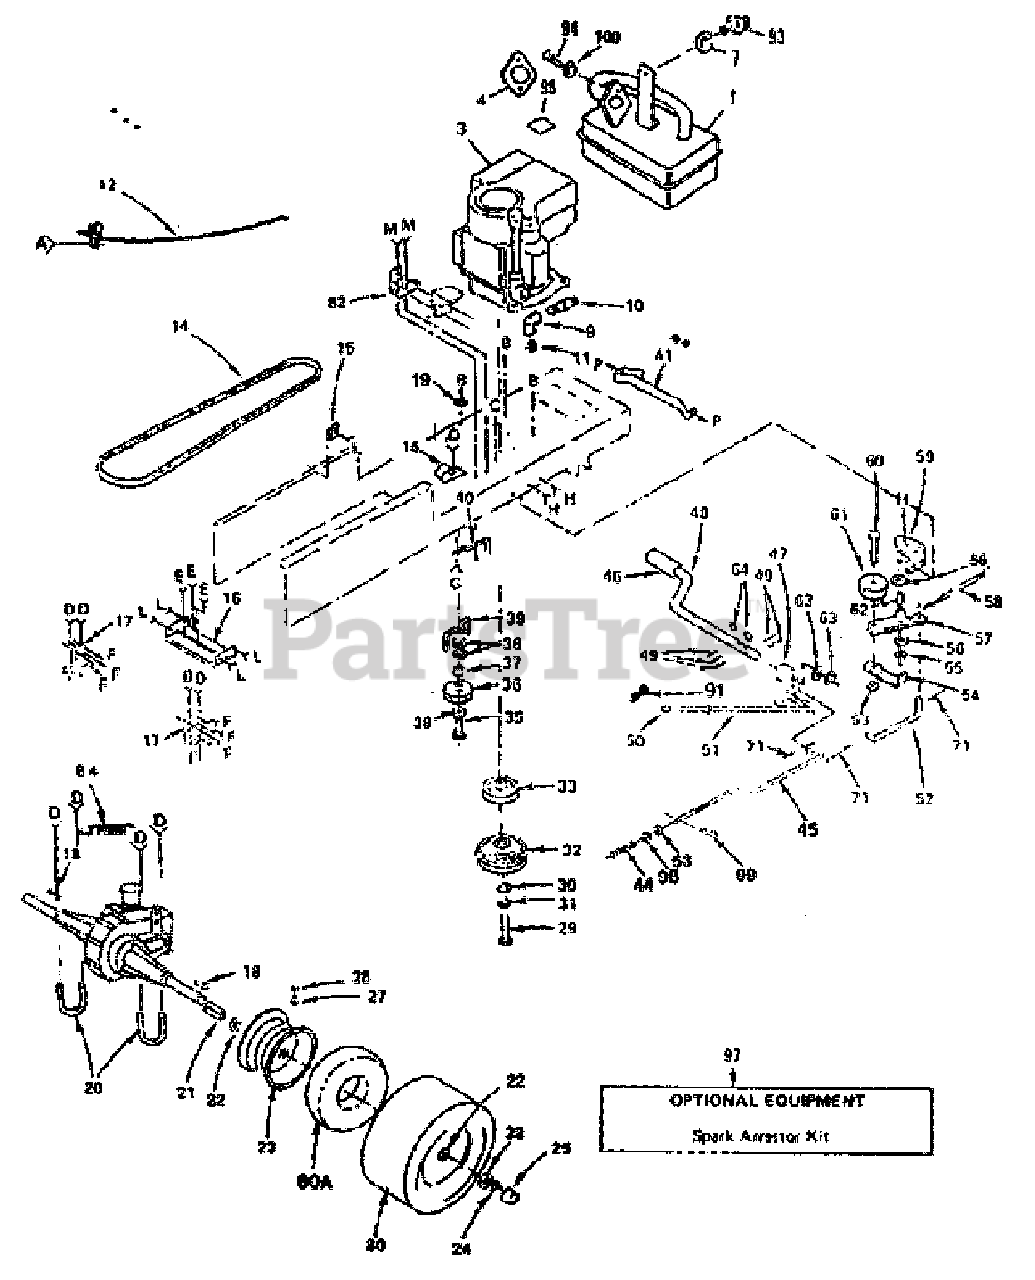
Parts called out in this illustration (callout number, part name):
5	Deflector- Exhaust
12	Control.Throttle/Choke
14	V-Belt, Drive
15	Clip
16	Bracket.Mounting.Hydro T/A
17	Bracket, Transaxle
18	Key - Square 1/4 x 2
20	U-Bolt,3/8 - 16 x 2-3/4
21	Spacer, Split
22	Washer, 1-1/32 x 1-5/8 x 16 Ga,
23	Rim- Rear- 8"
25	Cap.Hub.Rear
27	Stem, Valve
28	Cap, Valve
29	Bolt, Hex 7/16 - 20 x 4
32	Clutch - Electric
33	Pulley - Engine
36	Idler, Flat
37	Spacer
38	Washer, 13/32 x 13/16 x 12 Ga.
39	Keeper, Belt
40	Keeper, Belt, Engine, L.H.
41	Clutch Retainer Assembly
44	Spring - Rod, Brake
45	Rod, Brake
46	Cover, Pedal
47	Arm, Brake
48	Shaft, Foot Pedal
49	Pin, Roll,3/16 x 1
50	Cap
51	Rod, Brake, Park
52	Link, Clutch
54	Retainer, Belt
56	Washer, Hardened
57	Arm.Asm.Idler
58	Spring, Return, Clutch
59	Bracket.Support.Clutch
61	Pulley.ldler
63	Washer, 25t32x 1-1/4x 16Ga.
64	Key, Woodruff No, 9
80	Tire - 18 x 9.50 x 8
80A	Tube
82	Bracket - Switch
83	Screw-Tap. Hex Hd, No.10-24 x 1/2 Type T
84	Spring, Brake Return
88	Washer 9/32 x 5/8 x 16 Ga.
89	Bolt - Rd. Hd. Sq. Nk.5/16 - 18 x 3/4
91	Spring- Retainer
97	Spark Arrestor Kit
98	Nut, Hex Jam 3/8 X 16 UNC
99	Clip, Hairpin
